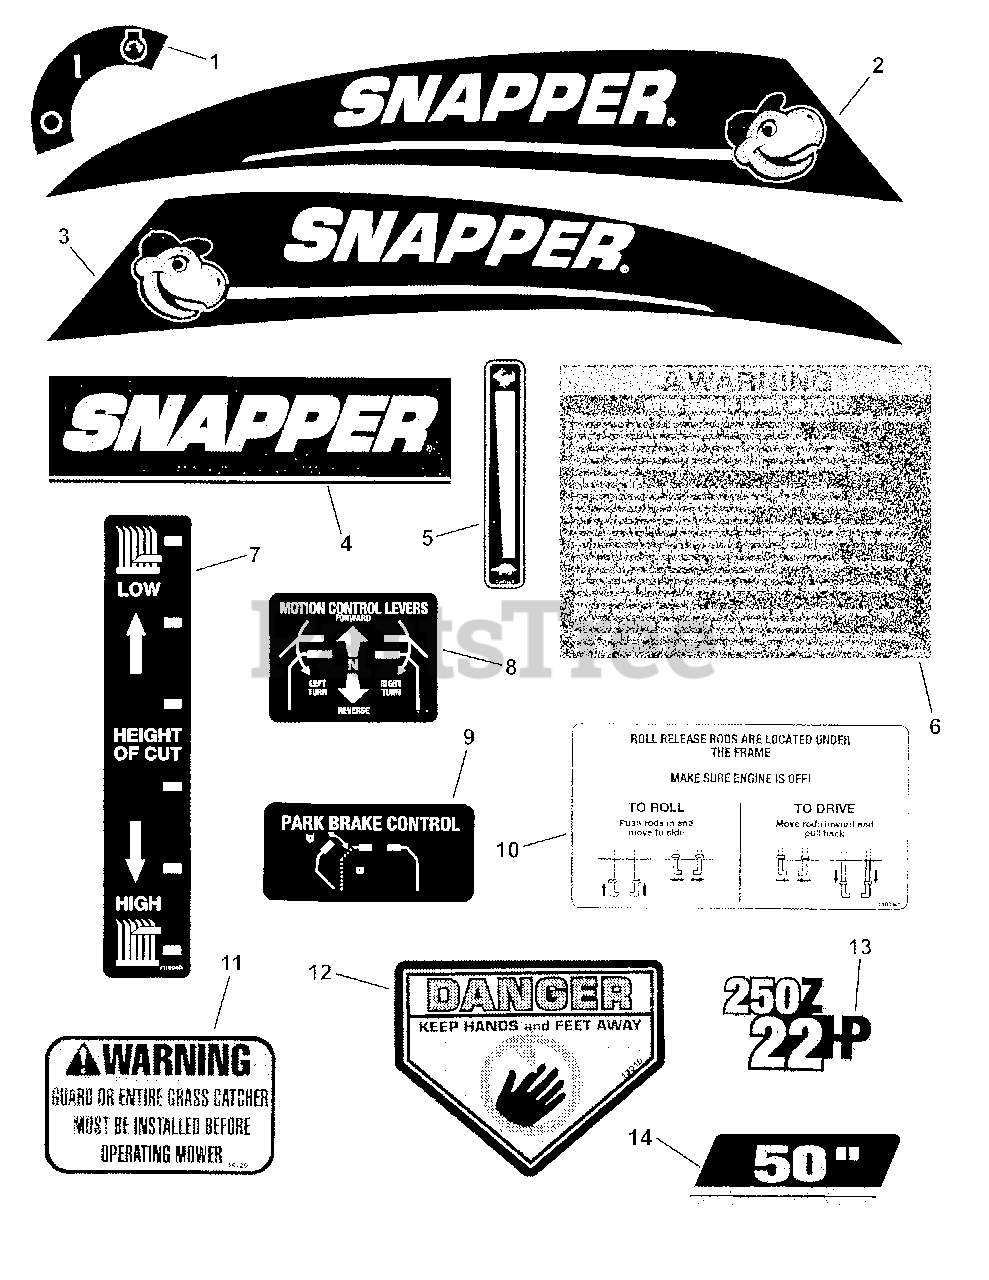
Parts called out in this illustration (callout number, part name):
1	DECAL, Ignition, RZT
2	DECAL, Snapper Fender, RH
3	DECAL, Snapper Fender, LH
4	DECAL, SNAPPER
5	DECAL, Throttle Control, RZT
6	DECAL, Warning, Operation
7	DECAL, Height Of Cut, RZT
8	DECAL, Motion Control, RZT
9	DECAL, Park Brake, RZT
10	DECAL, Roll Release, RZT
11	DECAL, Chute/Deflector
12	DECAL, Danger, (Cut Finger)
13	DECAL, 250 Z 22HP RZT
14	DECAL-50"-Silver on black w/stripe
